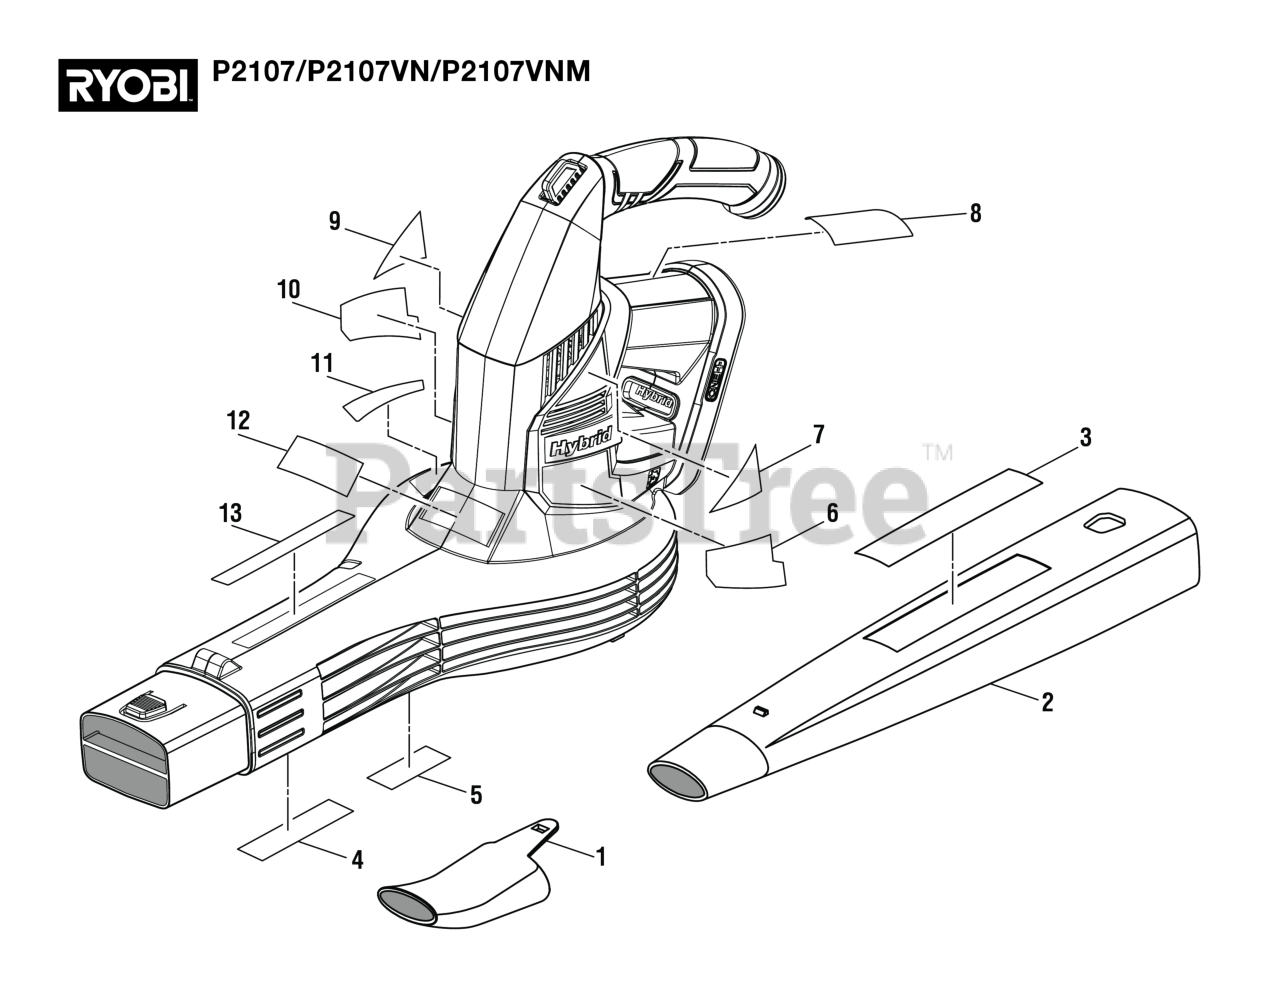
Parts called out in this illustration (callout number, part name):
1	High Velocity Nozzle
2	Blower Tube
3	Blower Tube Logo Label
4	Warning Label (French/Spanish)
5	Data Label
6	Left Bottom Label
7	Left Top Label
8	Hybrid Icon Label
9	Label, Top, Right
10	Right Bottom Label
11	Warning Label (English)
12	Logo Label
13	Warning Icon Label
